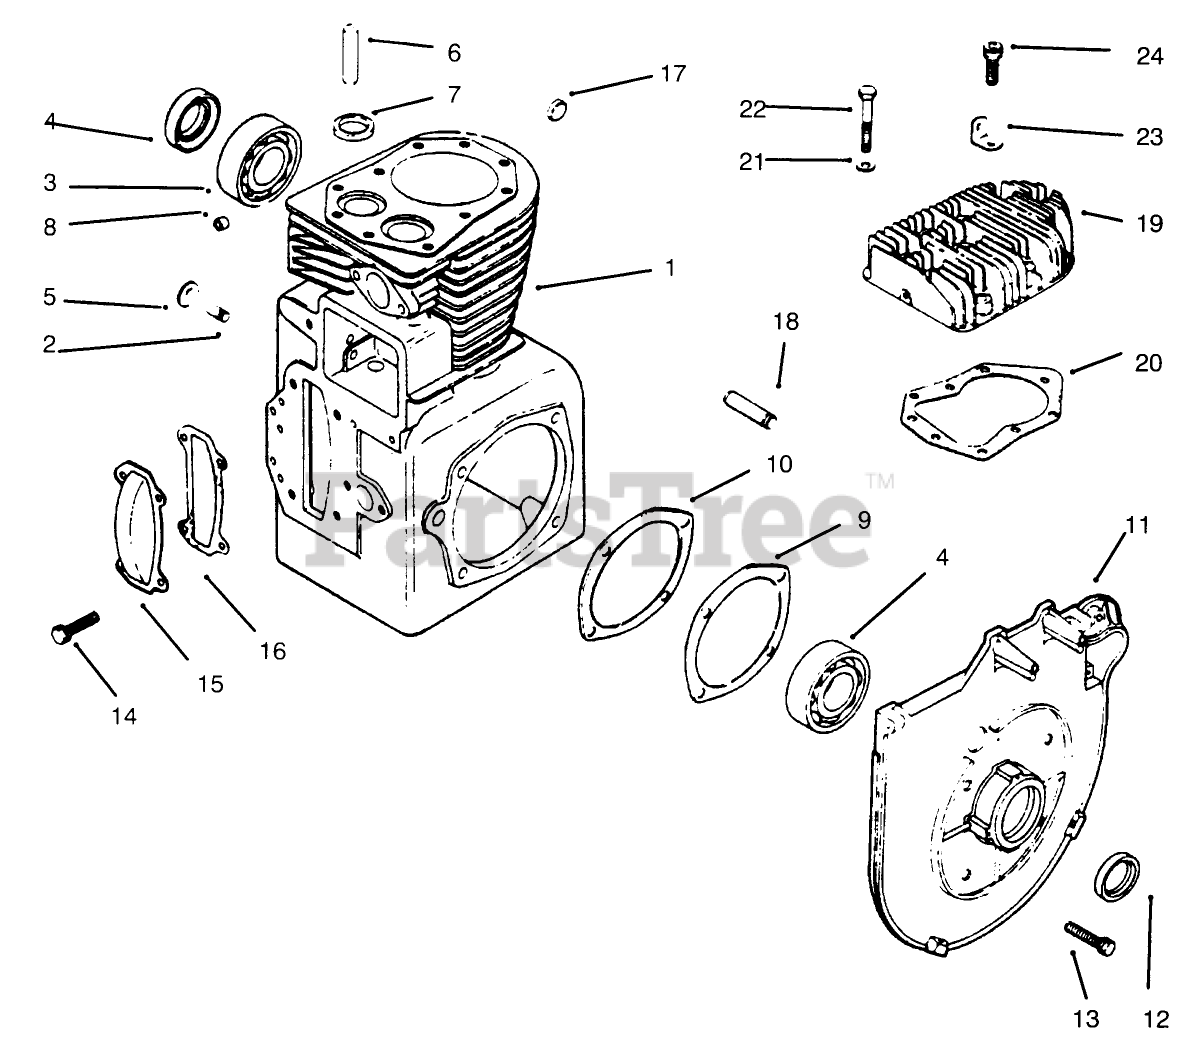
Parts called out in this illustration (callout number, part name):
1	Short Block 14hp
1	Miniblock W/Out Crank
2	Shaft-Govemor
3	Ball Bearing
4	Seal
5	Plug
6	Guide Valve
7	Insert
8	Bearing
9	Gasket
10	Gasket
11	Plate-Bearing
12	Seal
13	Screw
14	Screw
15	Cover
16	Gasket
18	Shaft
19	Head-Cylinder
20	Gasket
21	Washer
22	Screw
23	Strap-Lifting
24	Screw
